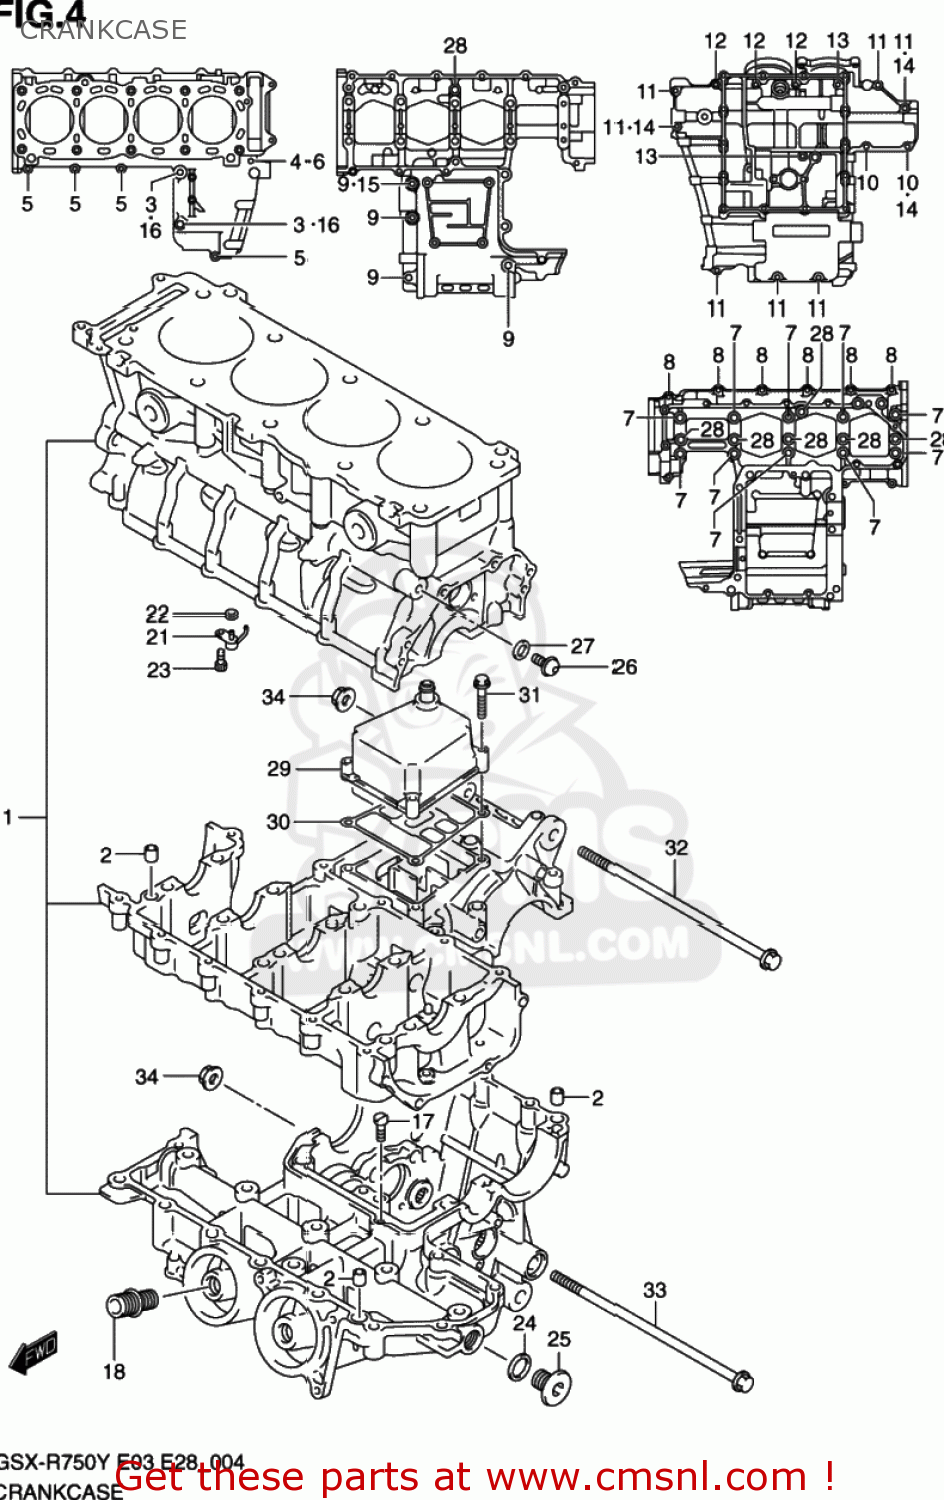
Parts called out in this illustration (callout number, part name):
1	CRANKCASE SET
2	PIN,CRANKCASE
3	BOLT(8X120)
4	GASKET(5.8X13X1.2) (NAS)
5	BOLT
6	BOLT
7	BOLT(9X95)
8	BOLT
9	BOLT
10	BOLT,G/S SWITC
11	BOLT
12	BOLT
13	BOLT
14	GASKET(5.8X13X1.2) (NAS)
15	GASKET(8.2X14X1) (NAS)
16	GASKET(8.2X14X1) (NAS)
17	JET(140)
18	UNION,OIL STAND
19	BEARING,CRANK THRUST(GREEN)
20	BEARING,CRANK THRUST(RED)
21	JET,PISTON COOLING
22	O RING(D:1.2,ID:4)
23	BOLT(6X12)
24	GASKET(16X22X2) (NAS)
25	PLUG
26	PLUG(10X10)
27	GASKET(10X14X3.6) (NAS)
28	O RING(D:1.9,ID:7.8)
29	COVER,BREATHER
30	GASKET,BREATHER COVER (NAS)
31	BOLT
32	BOLT 10X215
33	BOLT 10X215
34	NUT
